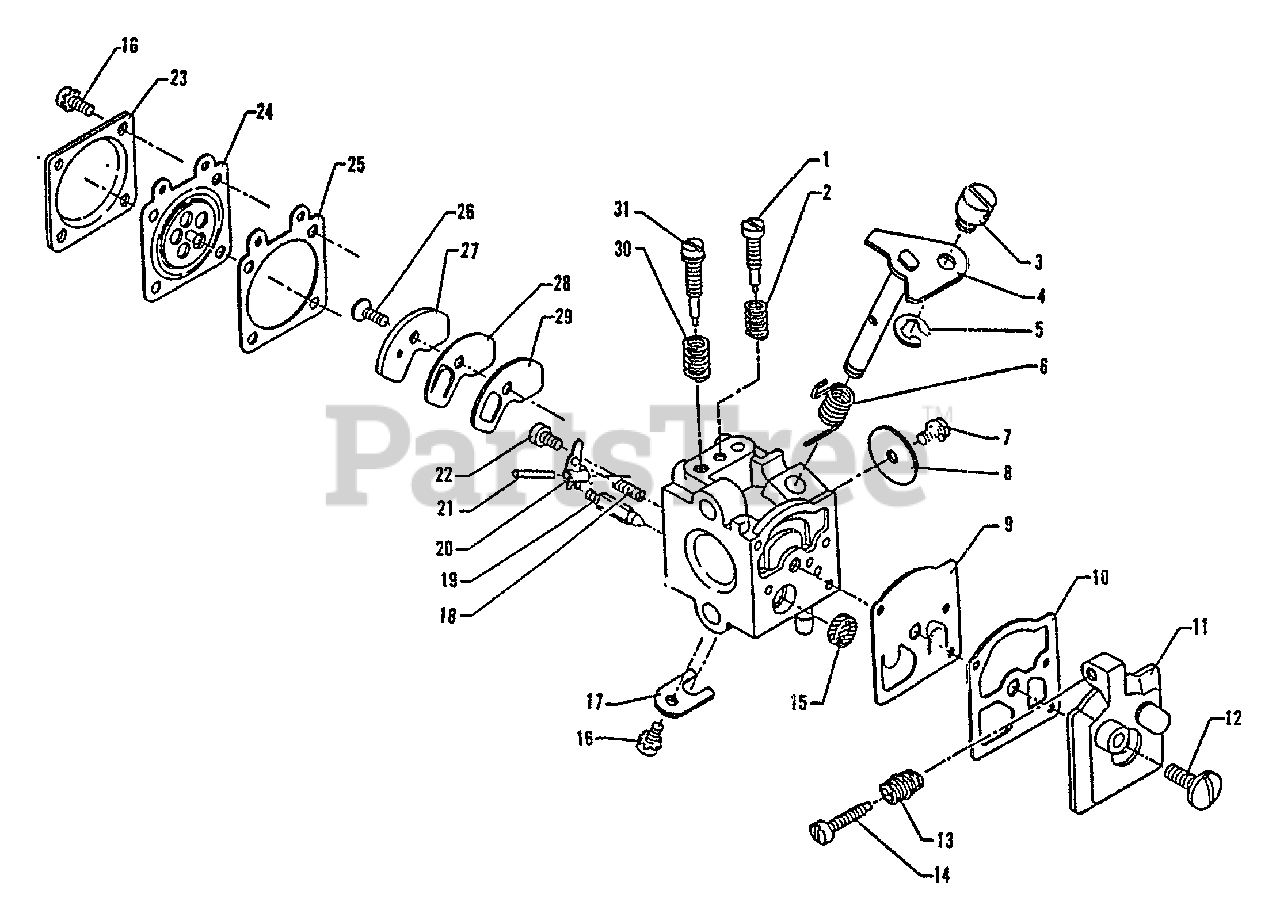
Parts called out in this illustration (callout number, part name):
1	NEEDLE - LOW SPEED
2	SPRING, NEEDLE RETURN
4	SHAFT, THROTTLE
5	RING, RETAINING
6	SPRING, THROTTLE RETURN
8	VALVE, THROTTLE
9	DIAPHRAGM, PUMP
10	GASKET, PUMP
11	COVER, PUMP
12	SCREW, PUMP COVER
13	SPRING, IDLE ADJUST
14	SCREW, IDLE ADJUST
15	STRAINER
16	SCREW
17	CLIP, THROTTLE SHAFT
18	SPRING, METERING LEVER
19	VALVE, INLET NEEDLE
20	LEVER, METERING
21	PIN, METERING LEVER
22	SCREW, METERING LEVER PIN
23	COVER, METERING
24	DIAPHRAGM, METERING
25	GASKET, METERING
26	SCREW
27	PLATE, CIRCUIT
28	DIAPHRAGM, CIRCUIT PLATE
29	GASKET, CIRCUIT PLATE
30	SPRING
31	NEEDLE - HIGH SPEED
